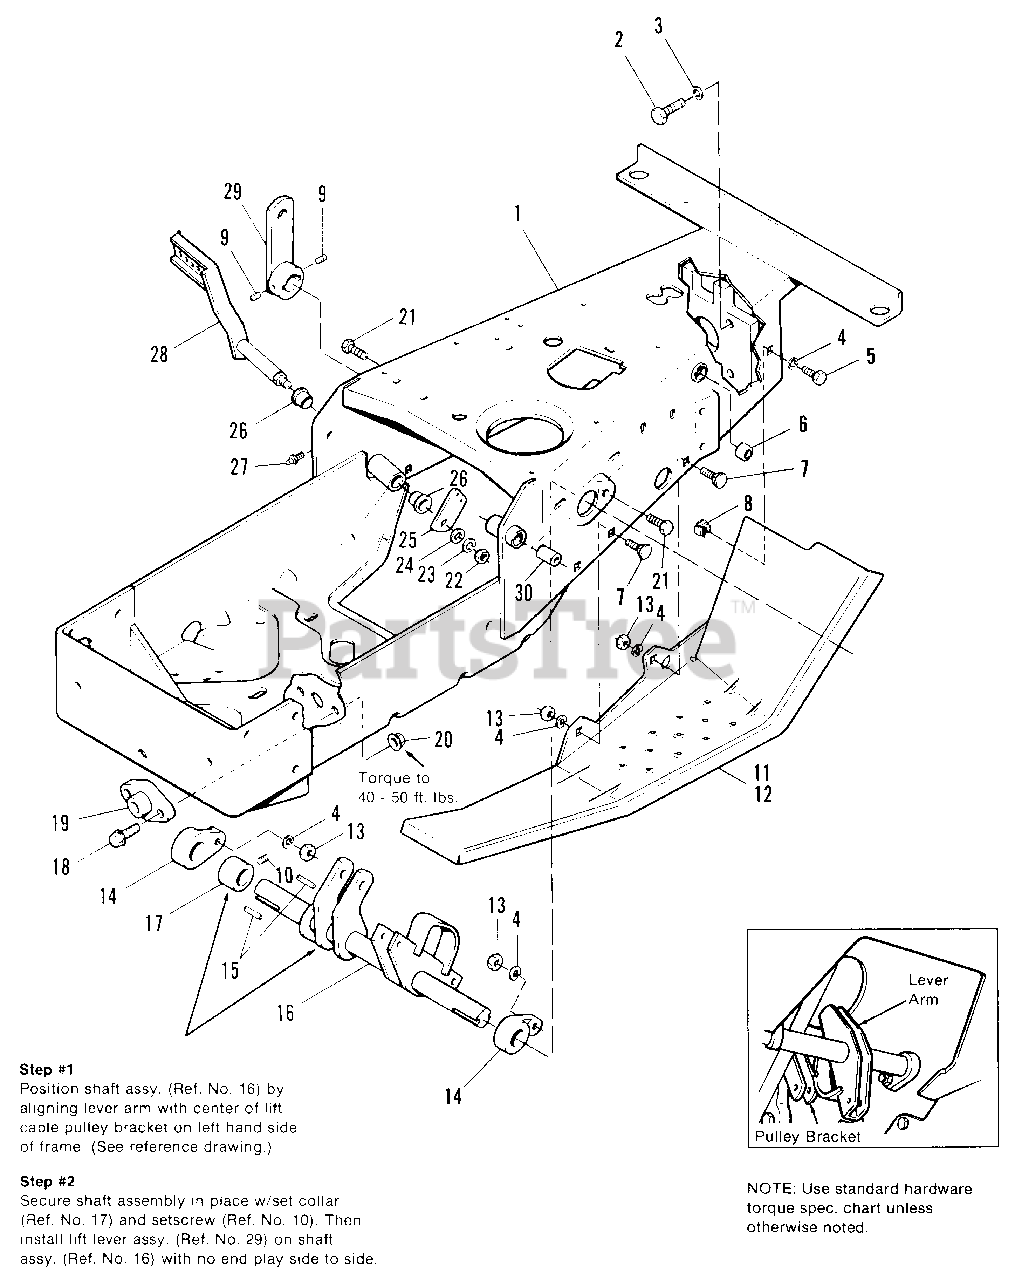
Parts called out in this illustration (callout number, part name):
1	FRAME ASSY., w/Bushings (1691382)
1	FRAME ASSY., w/Bushings (1691717 & 1691957)
2	CAPSCREW, Hex Hd., 7/16-14 x 1-1/2
3	LOCKWASHER, 7/16
4	LOCKWASHER 5/16
5	CAPSCREW, Hex Hd., 5/16-18 x 3/4
7	BOLT, Carriage, 5/16-18 x 3/4
8	NUT, Speed, 5/16-18
9	SETSCREW, 5/16-18 x 1/4
10	SETSCREW, 5/16-18 x 1/2
11	FOOTREST, LH
12	FOOTREST, RH.
13	NUT, Hex, Full, 5/16-18
14	BEARING, Lift Lever
16	SHAFT ASSY., Lift (Hydro Lift)
16	SHAFT ASSY., Lift (Manual Lift)
17	COLLAR, Set
18	SCREW, Hex, Whiz, Flange, 3/8-16 x 1-1/4
19	BEARING, Pivot
20	LOCKNUT, Hex, Flange, 3/8-16
21	CAPSCREW, Hex Hd ., 5/16-18 x 1-1/4
22	NUT, Hex, Full, 3/8-16
23	LOCKWASHER, 3/8
24	WASHER, Plain, 3/8
25	ARM, Foot Pedal
27	FITTING, Grease
28	PEDALASSY., Foot
29	LEVER ASSY., RH
30	BEARING, Interim Pinion
